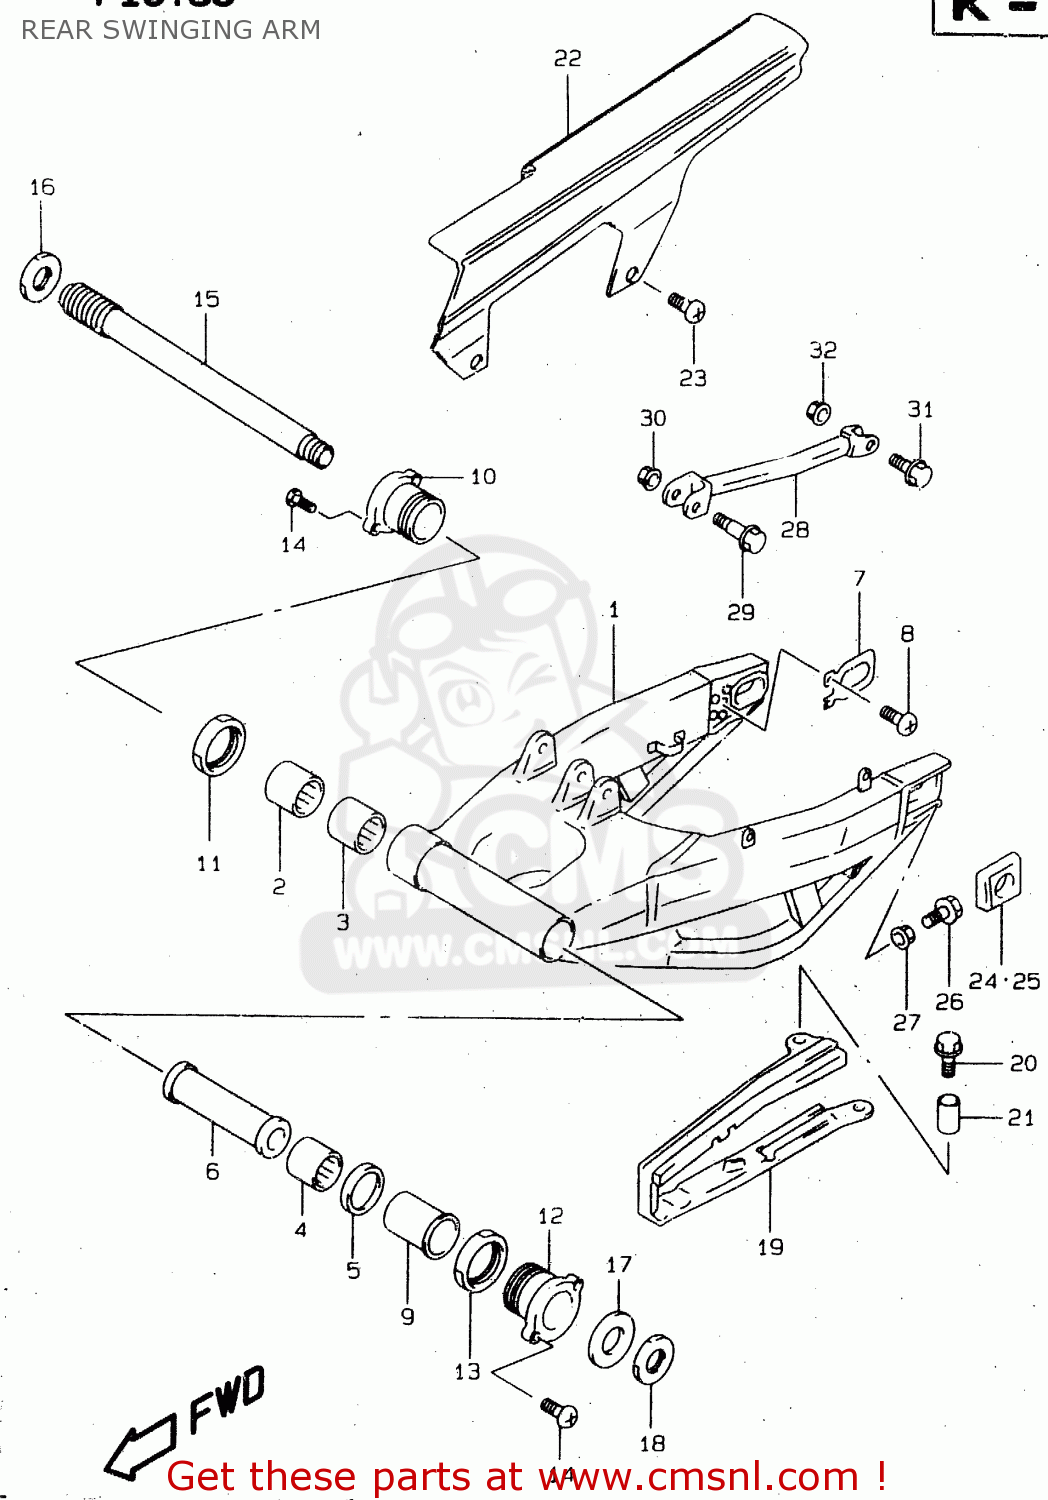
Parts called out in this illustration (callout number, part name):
1	SWINGINGARM ASSY,RR
2	BEARING(25X52X15)
3	BEARING
4	BEARING(30X40X25)
5	SEAL,OIL(30X40X6)
6	SPACER,REAR SWING PIVOT,CENTER
7	PLATE,RR SWING ARM BRKT
8	SCREW 6X10
9	SPACER,SWINGINGARM PIVOT BRG
10	BOSS,RR SWINGINGARM PIVOT,R
11	NUT,RR SWGARM PIVOT BOSS,R
12	BOSS,RR SWINGINGARM PIVOT,L
13	NUT,RR SWGARM PIVOT BOSS,L
14	SCREW
15	SHAFT,RR SWINGINGARM PIVOT
16	NUT,REAR SWING ARM PIVOT
17	WASHER(25.2X42X3.2)
18	NUT
19	BUFFER,CHAIN TOUCH DEFENSE
20	BOLT 6X20,WITH PLAIN WASHER
21	SPACER(6.5X9X5)
22	CASE,CHAIN
23	SCREW(6X16)
24	ADJUSTER,CHAIN,R
25	ADJUSTER,CHAIN,L
26	BOLT(8X50)
27	NUT
28	TORQUELINK,RR
29	BOLT(8X35.5)
30	NUT
31	BOLT(10X37)
32	NUT
